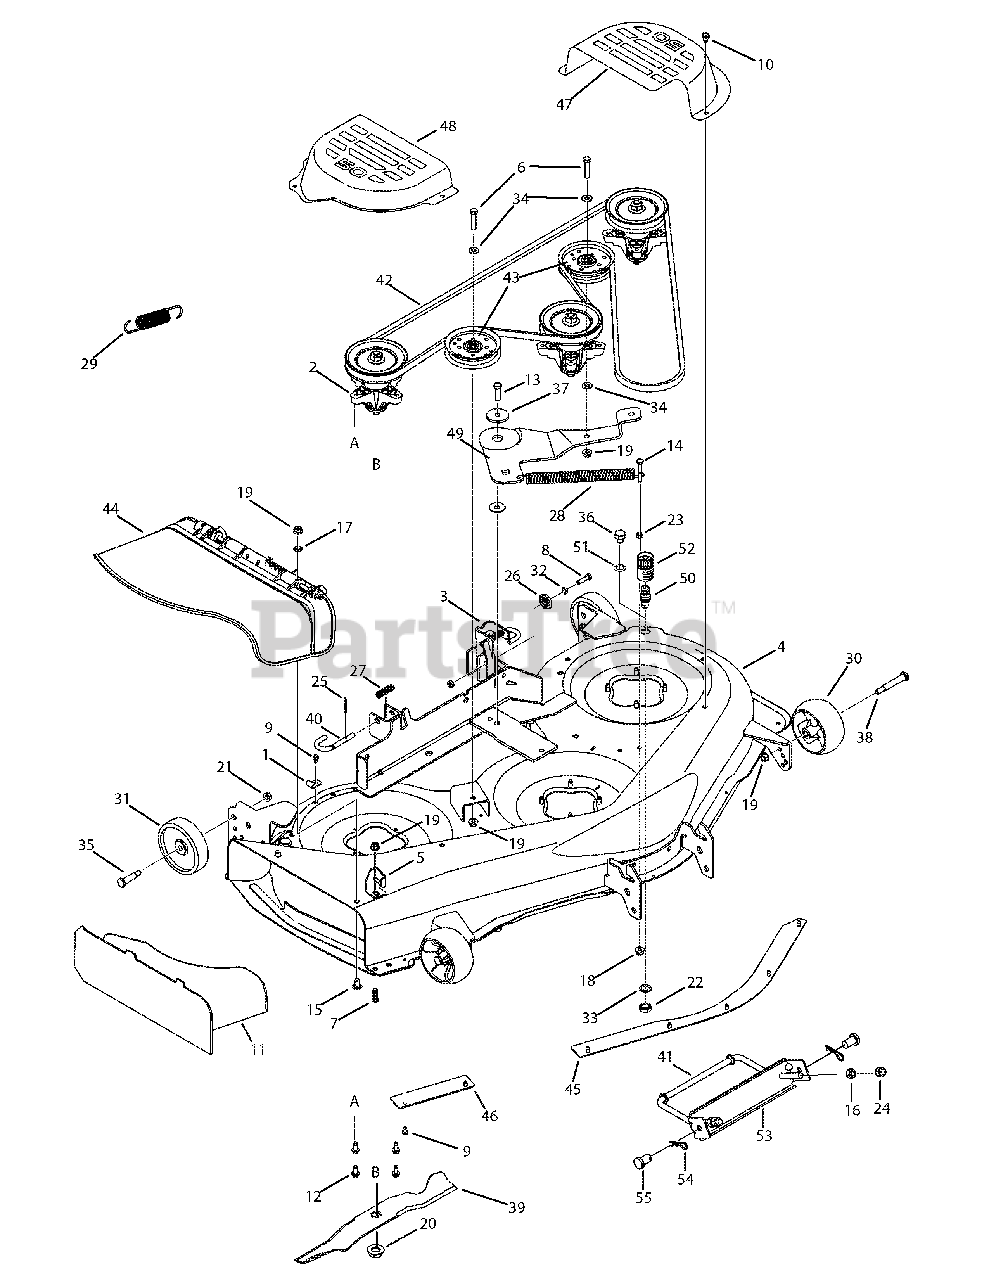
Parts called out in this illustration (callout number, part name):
1	Hook, Retainer
2	Spindle Assembly
3	Hanger Bracket Assembly
4	Weldment, 50-inch Deck
5	Chute Stop
6	Screw, 3/8-16, 1.75
7	Screw, 3/8-16 x 1.0
8	Screw, 5/16-18, 1.25, Gr5
9	Screw, 1/4-20 x 0.5
10	Screw, 5/16-18, .500
11	Mulch Plug
12	Screw, 5/16-18, .750
13	Screw, 3/8-16, 1.25
14	Screw, 5/16-18 x 2.00
15	Screw, Carriage, 3/8-16 x .75
16	Hex Nut, 1/2-13
17	Push Nut Retainer
18	Nut, Nylon Lock, 5/16-18
19	Nut, Nylon Lock, 3/8-16
20	Nut, Hex, Flange, 5/8-18
21	Nut, Nylon Lock, 3/8-16, Top Lock
22	Nut, Hex, M16-1.5
23	Nut, Hex, 5/16-18, Gr5
24	Hex Lock Nut, 1/2-13
25	Pin, Cotter, 1/8 x 1.25
26	Deck Adjustment Gear
27	Spring, Compression, .531 x 1.75
28	Spring, Extension, .94 x 6.74
29	Spring, Lift Assist
30	Deck Wheel, 5.0
31	Deck Wheel, 5.0
32	Washer, Lock, 5/16
33	Lock Washer, 5/8"
34	Washer, Flat, .406 x .875 x .059
35	Shoulder Screw
37	Spacer, Shoulder, .884 x .190
38	Shoulder Screw
39	Blade, 17.90
40	Rod, Deck Release .375 Dia.
41	Rod, Deck Adjust
42	Belt, V-Type
43	Pulley, Idler, 3.5"
44	Chute Assembly, Side Discharge
45	Deck Skirt, Center
46	Deck Skirt, RH
47	LH Belt Cover
48	RH Belt Cover
49	Idler Bracket
50	Port, Water
51	Flat Washer, .64 x 1.24 x .06
52	Water Nozzle Adapter
53	Front Deck Rod Adjustment Bracket
54	Cotter Pin
55	Clevis Pin, .50 dia. x .78 lg.
